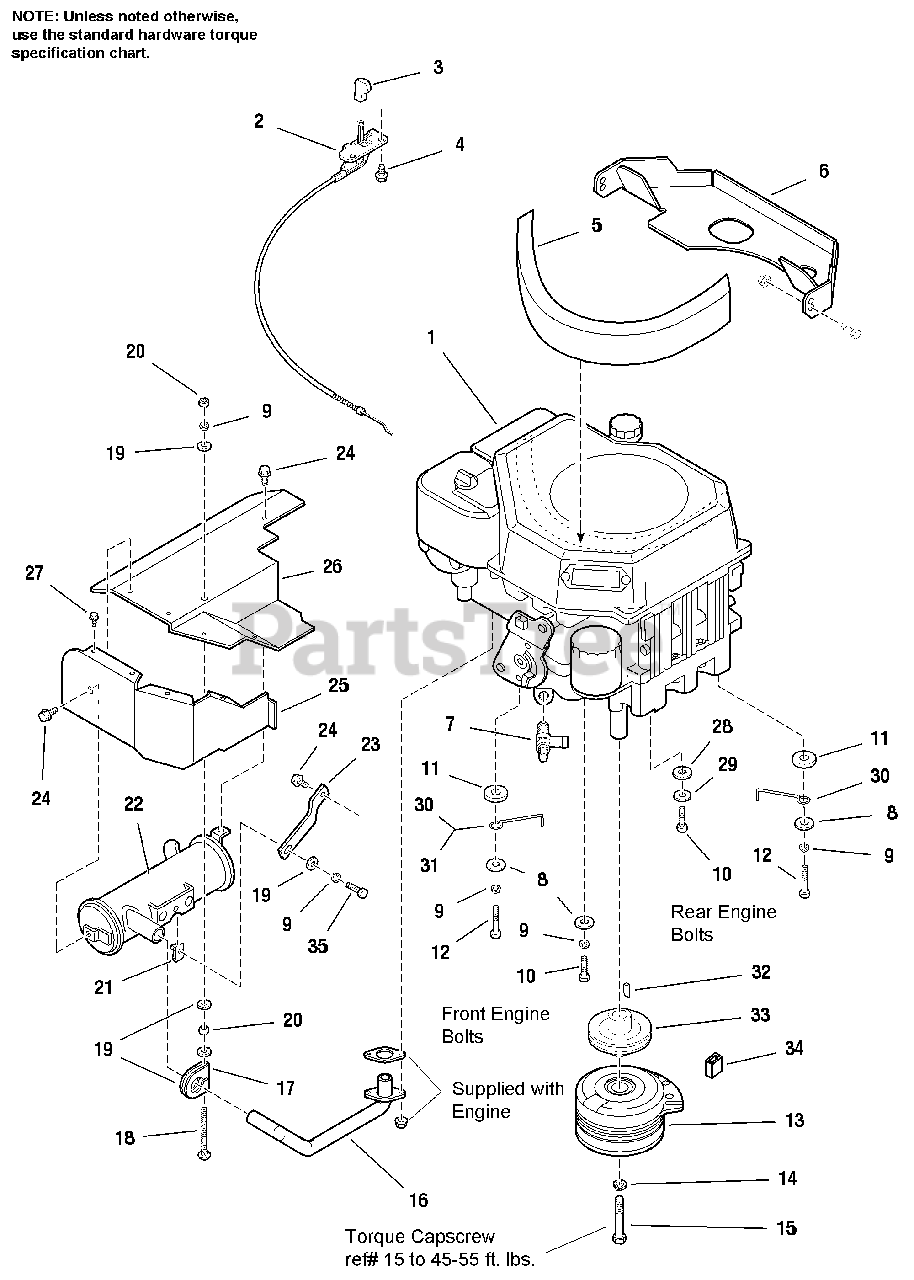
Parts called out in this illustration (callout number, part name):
1	ENGINE ASSEMBLY, 14 HP Kohler
2	THROTTLE CONTROL ASSEMBLY
3	KNOB, Throttle
4	SCREW, Plastite, 1/4-10 x 1/2
5	SEAL, Air Inlet
7	VALVE, Shut Off
8	WASHER, Plain, 5/16
9	LOCKWASHER, 5/16
10	SCREW, Hex, #8 - 1.25 x 30mm
11	WASHER, Plain
12	CAPSCREW, Hex Hd., M08 - 1.25 x 40mm
13	CLUTCH, Electric
14	LOCKWASHER, 7/16
15	CAPSCREW, Hex, 7/16-20 x 2-1/2
16	PIPE, Exhaust
17	CLAMP, Muffler
18	CARRIAGE BOLT, 5/16-18 x 3-1/4
19	WASHER, 5/16
20	NUT, Hex, 5/16-18
21	NUT, Speed, 5/16-18
22	MUFFLER ASSEM.
23	SUPPORT, Muffler
24	SCREW, Hex, Taptite, 5/16-18 x 1/2
25	AIR DUCT, Bottom
26	SHIELD, Muffler
27	SCREW, Hex, Thd. Form, #10-16 x 3/8
28	WASHER, Plain, 5/16
29	LOCKWASHER, Internal Tooth, 5/16
30	BELT STOP
30	BELT STOP, Rear
31	BELT STOP, Front
32	KEY, Hi-Pro
33	PULLEY, Engine
34	SLEEVE, Clutch Anchor
35	CAPSCREW, Hex Hd 5/16-18 x 1
